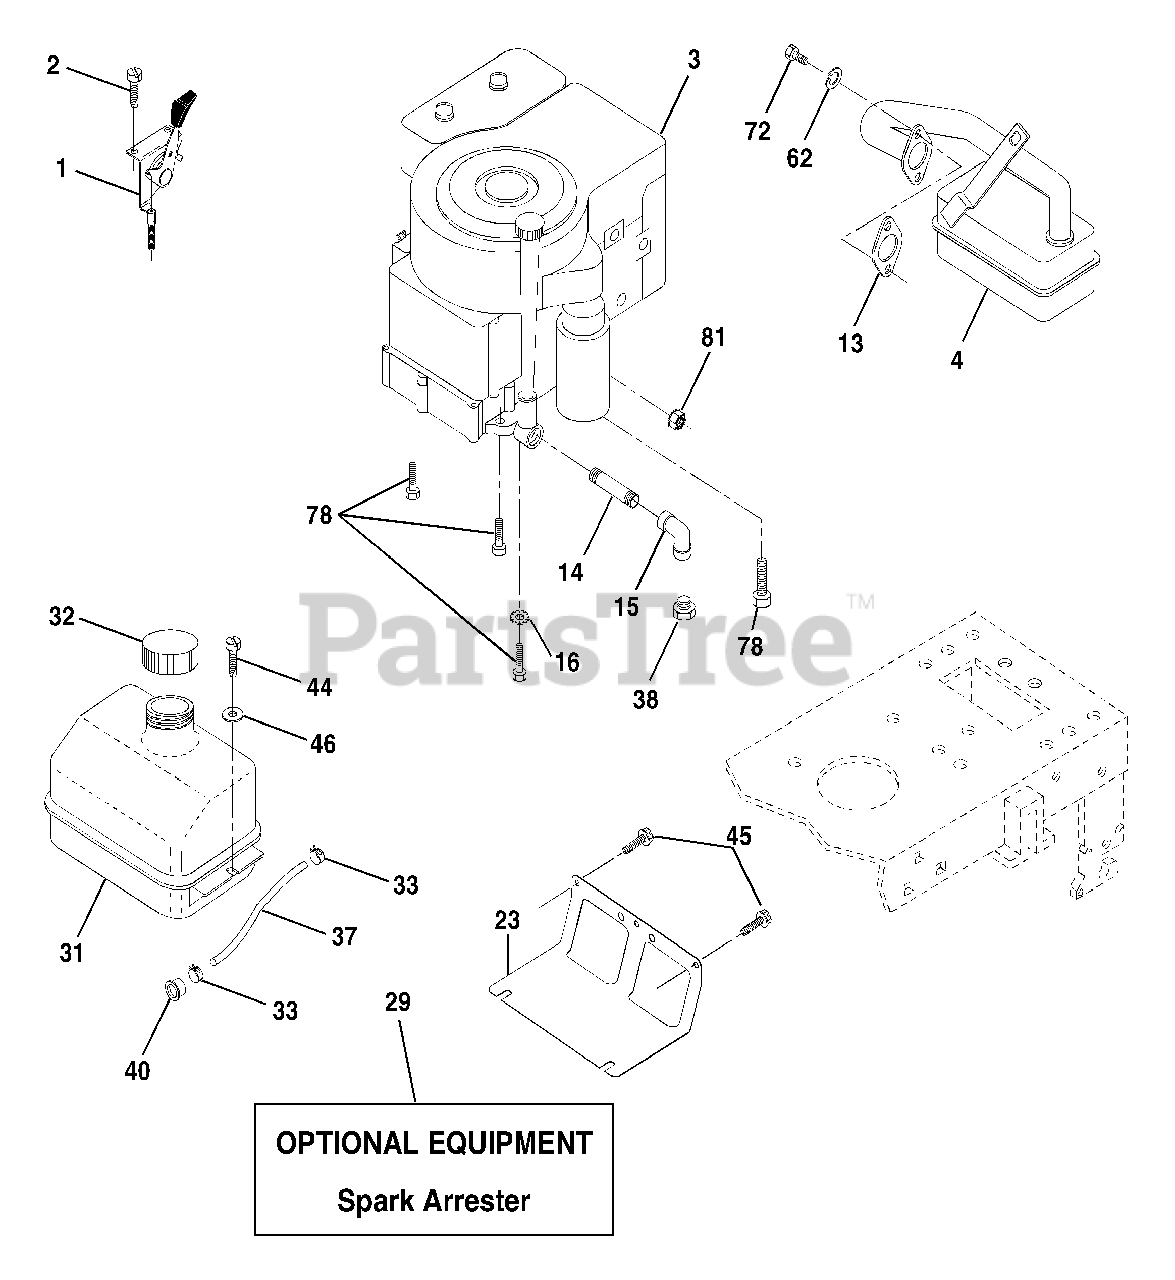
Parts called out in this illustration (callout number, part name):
1	Control Throt /Ch Flag
2	Screw Hex Thd Cut 1/4-20x1/2
4	Muffler Exhaust B&S Lt
13	Gasket 1 313 Id Tin Plated
14	Nipple Pipe 3/8 NPT x 3"
15	Elbow STD 90 Degree 3/8-18 NPT
16	Washer Lock Ext Tooth 3/8
23	Shield Browning/Debris Guard
29	Arrestor Spark
31	Tank Fuel 1 25 Fr
32	Cap Asm Fuel W/sym Vented
33	Clamp Hose Blk
37	Line Fuel 20"
38	Plug Drain Oil
40	Bushing Snap Nyl Blk Fuel Line
44	Screw Hexwsh Thdrol 1/4-20x3/4
45	Screw Hex Wsh Thdrol 3/8-16
46	Washer 9/32 X 7/8 X 16ga
62	Washer Lock Hvy Hlcl Spr 5/16
72	Screw Hexhd Cap 5/16-18x3/4
78	Screw Thdrol 3/8-16x1-1/4
81	Nut Keps Hex 1/4-20 Unc
